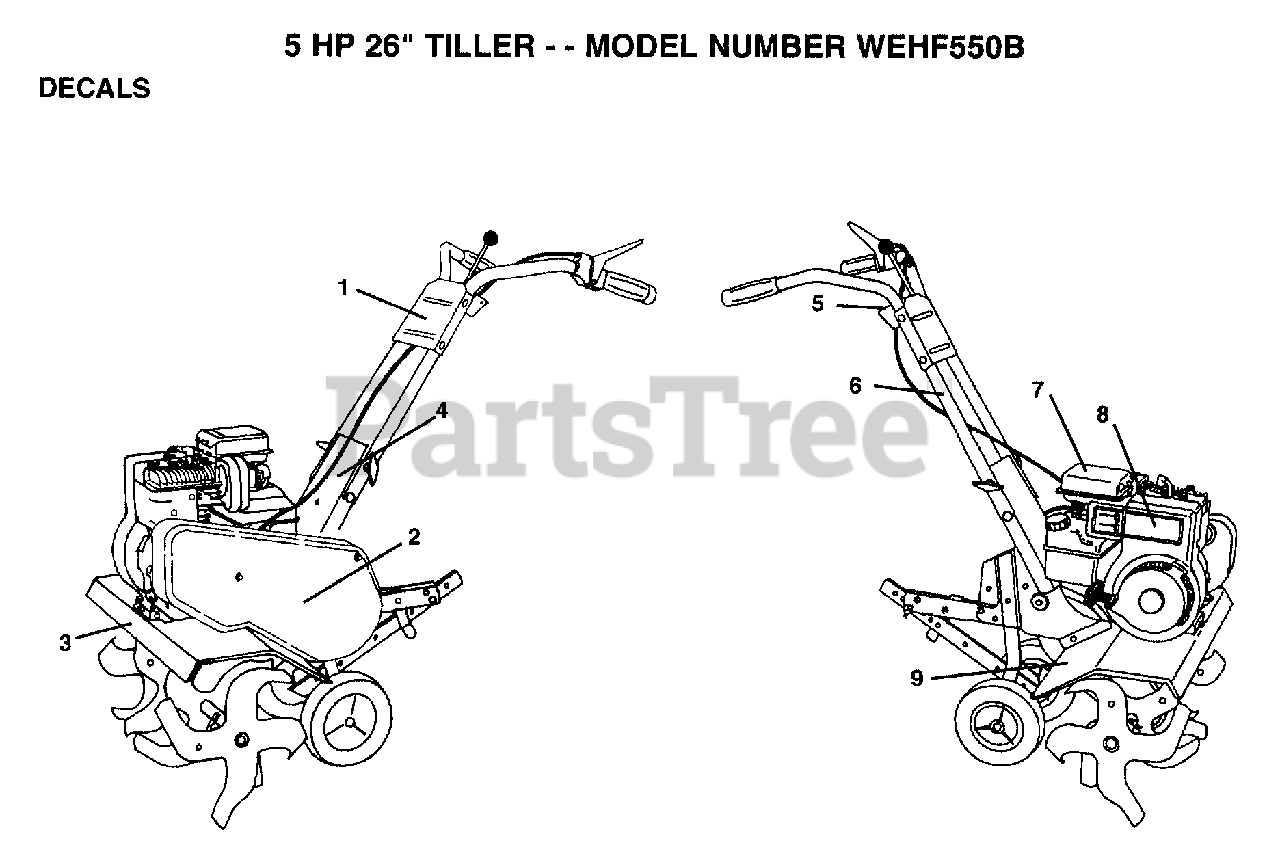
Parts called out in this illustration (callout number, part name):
2	DECAL.GUARD.BELT
3	DECAL.SHIELD.TINE
4	DECAL.PNL.HANDLE
5	DECAL.PNL.CTRL.ES
6	DECAL.HAND.PLACE
7	DECAL.CAUTION.E/S
9	DECAL.WARN.ROT.TI
